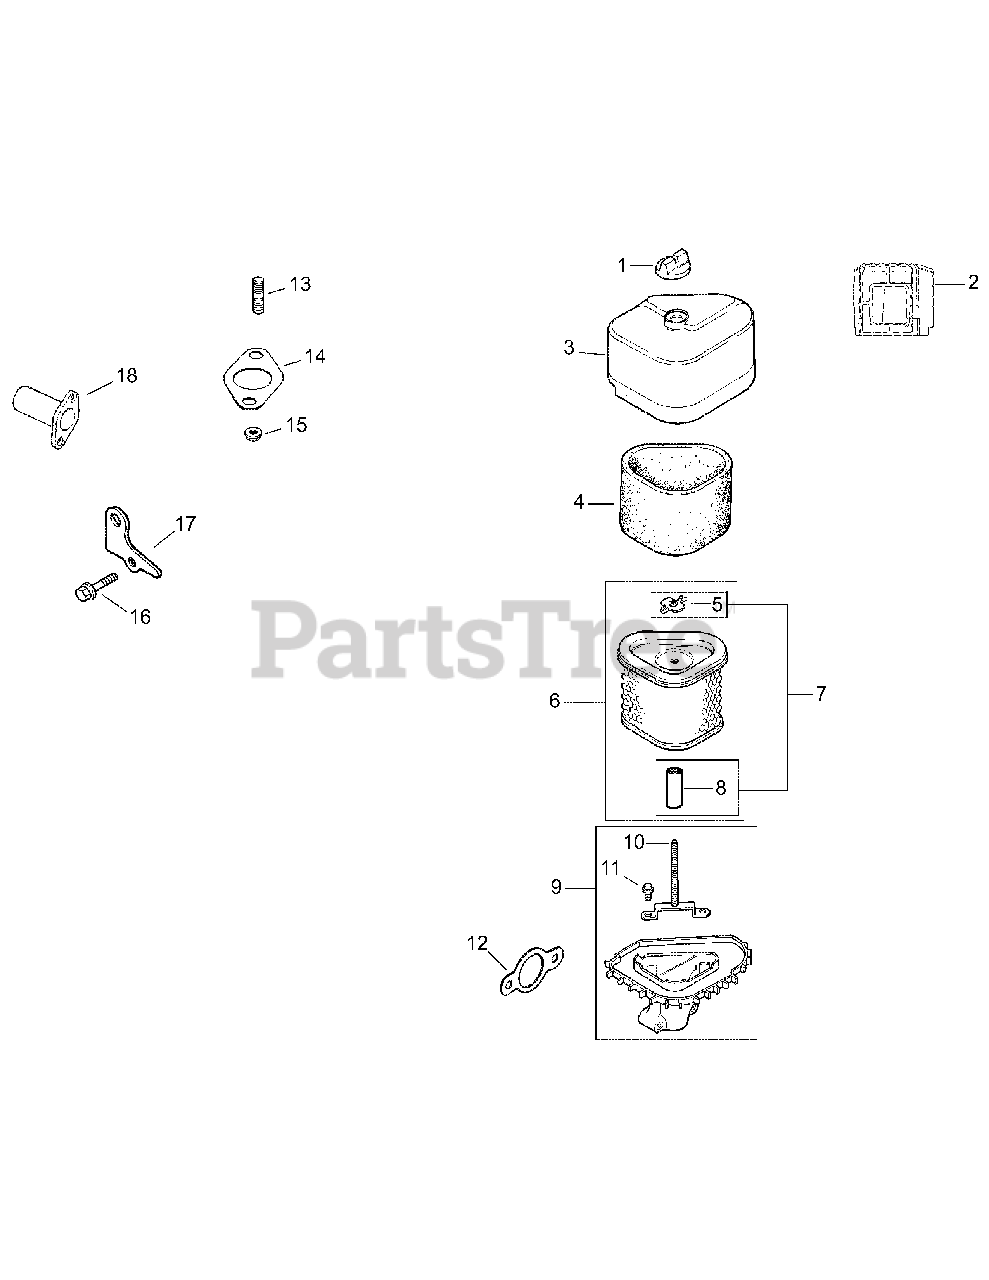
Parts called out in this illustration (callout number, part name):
1	Knob, Air Cleaner Cover
3	Cover, Air Cleaner
4	Precleaner
6	Element, Air Cleaner (Includes 5, 7, 8)
7	Kit, Air Cleaner Seal (Includes 5, 8)
9	Base, Air Cleaner (Includes 10, 11)
10	Stud M6 x 1.0 x 79
11	Screw, #10 Hi-Lo Thread Forming
12	Gasket, Air Cleaner
13	Stud M8 x 1.25 x 39
14	Gasket, Exhaust Manifold
15	Nut, Hex. Flange M8 x 1.25
16	Screw, Hex. Flange M6 x 1.0 x 25
17	Strap, Lifting
